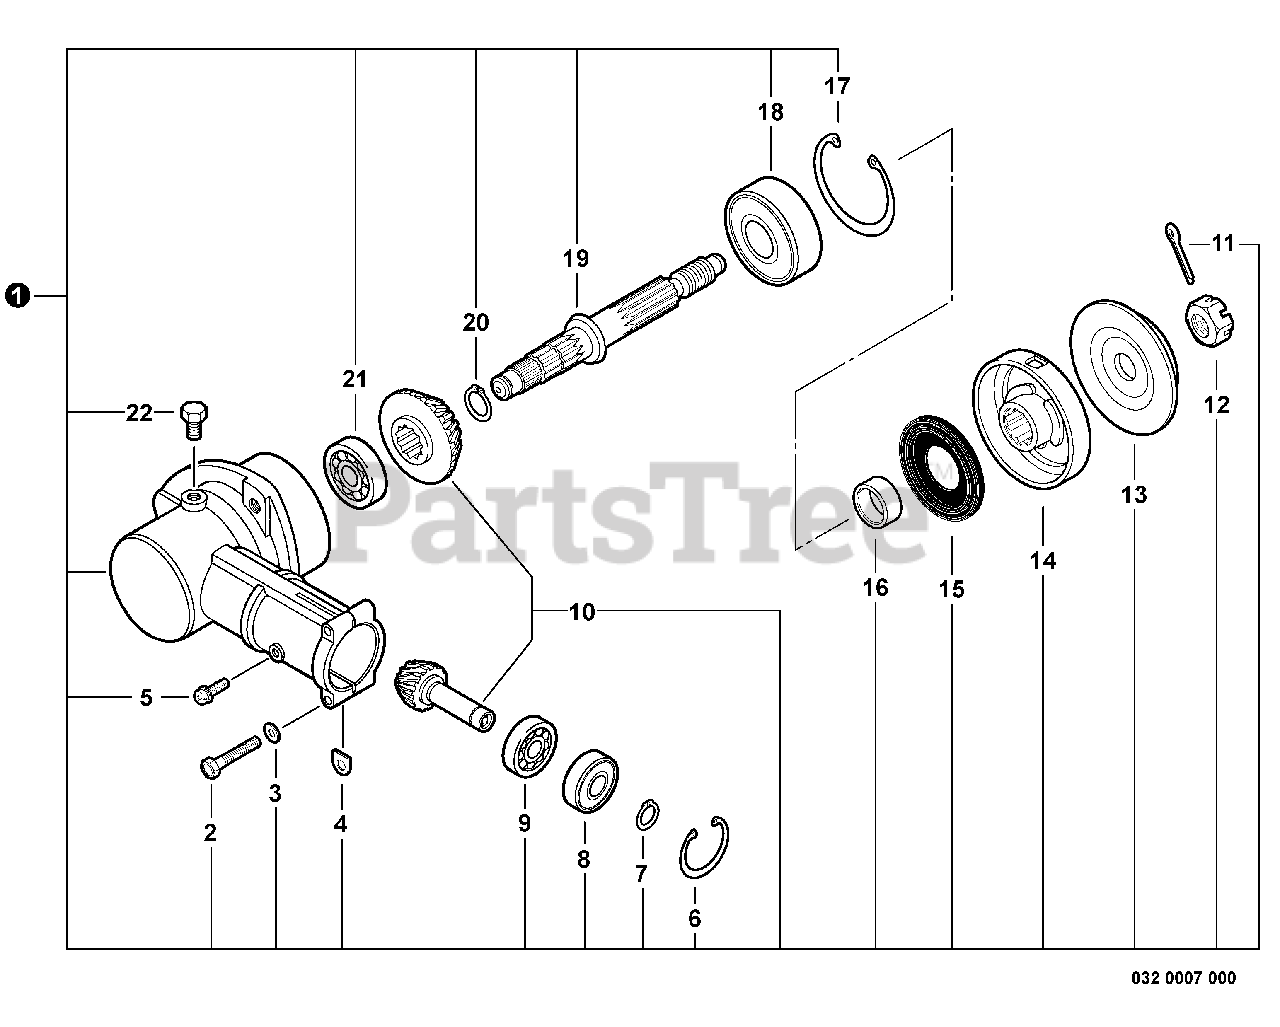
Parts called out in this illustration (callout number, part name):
1	GEAR CASE ASSY
2	BOLT 5×30
3	WASHER, FLAT 5.5×10×0.8
5	SCREW 5×10
6	RING, SNAP Ø22
7	RING, SNAP Ø10
8	BEARING, BALL 6900Z
9	BEARING, BALL 6900
10	GEAR SET
11	PIN, COTTER 2×22
12	NUT 10×1.25 LH
13	PLATE, ADAPTOR - LOWER
14	PLATE, ADAPTER - UPPER
15	SEAL, OIL 22
16	SPACER 11.8×15×9
17	RING, SNAP Ø32
18	BEARING, BALL - 6201 C3
19	SHAFT, GEAR
20	RING, SNAP Ø12
21	BEARING, BALL 609
22	BOLT 8×8 SP
